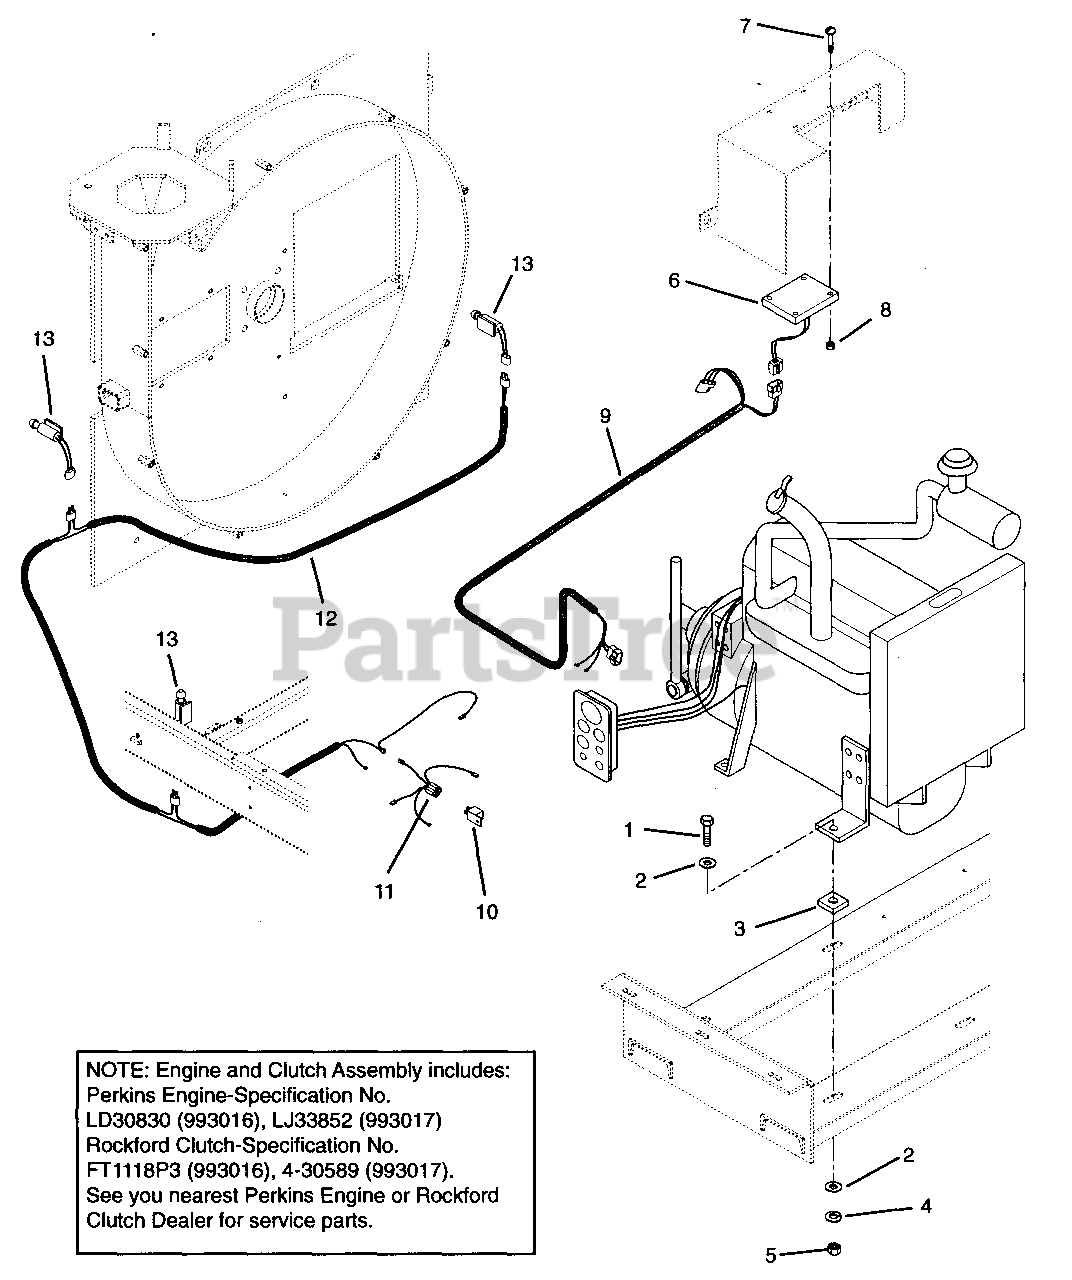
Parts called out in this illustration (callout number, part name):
1	Bolt - Hex .50-13 x 2.00
2	Washer-Flat-Steel .813 x 2.000 x .148
3	Engine Base Spacer
4	Washer-Lock .750 x .188
5	Nut .75-10
6	Module-Load Control
7	Screw-Machine 10-24 x 1.75 Slotted Pan Head
8	Nut-Keps 10-24
9	Wire Harness-Autofeed
10	Relay
11	Jumper Connection
12	Wire Harness-Safety Switch
13	Safety Switch
